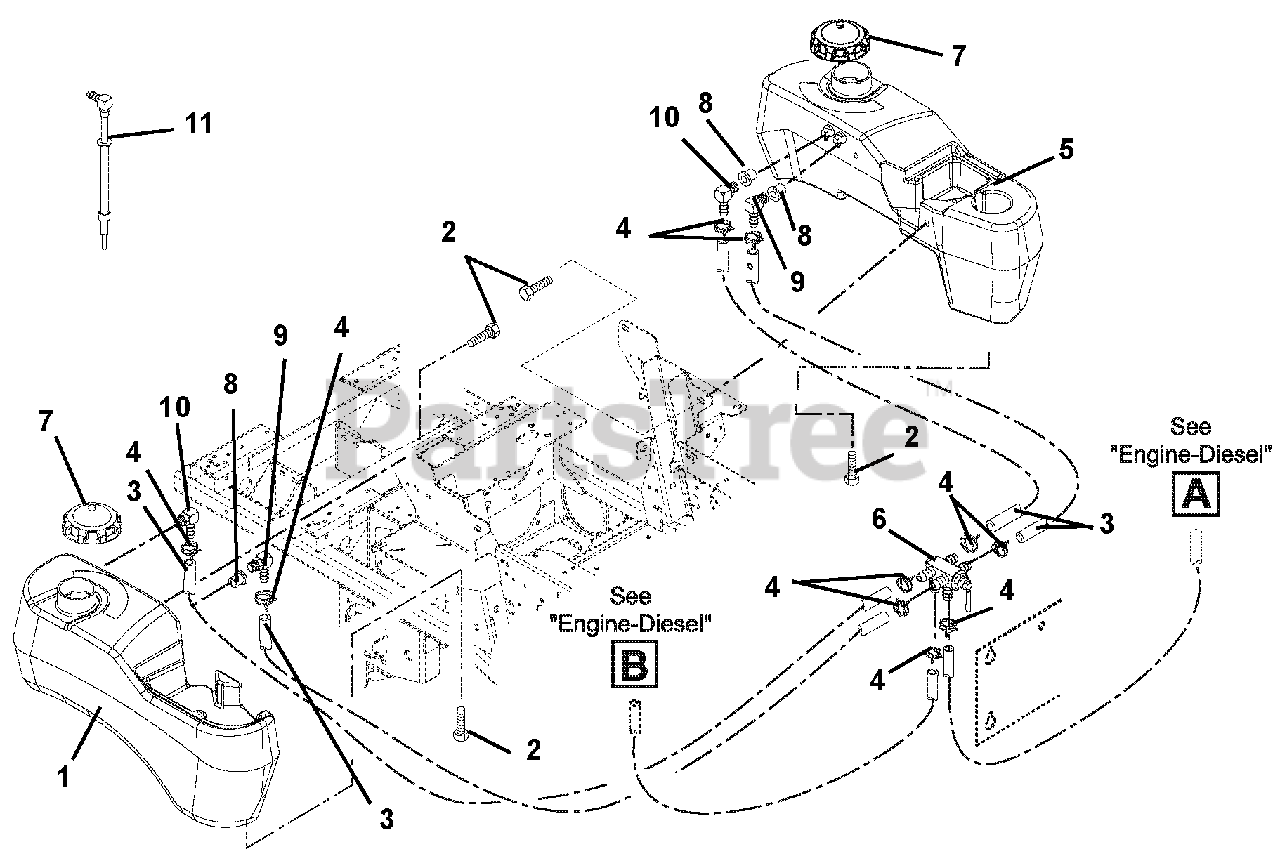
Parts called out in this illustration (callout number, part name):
1	Tank, Right Hand Fuel
2	Bolt, SEMS .31-18 x .62
3	Hose, .31 ID
4	Clamp, Hose Wire .52/.55
5	Tank, Left Hand Fuel
6	Valve, Fuel
7	Cap, Fuel
8	Grommet, Orange
9	Fitting, Tank
10	Fitting, Tank
11	26" Fuel Line Kit, Diesel (Inside Tank)
